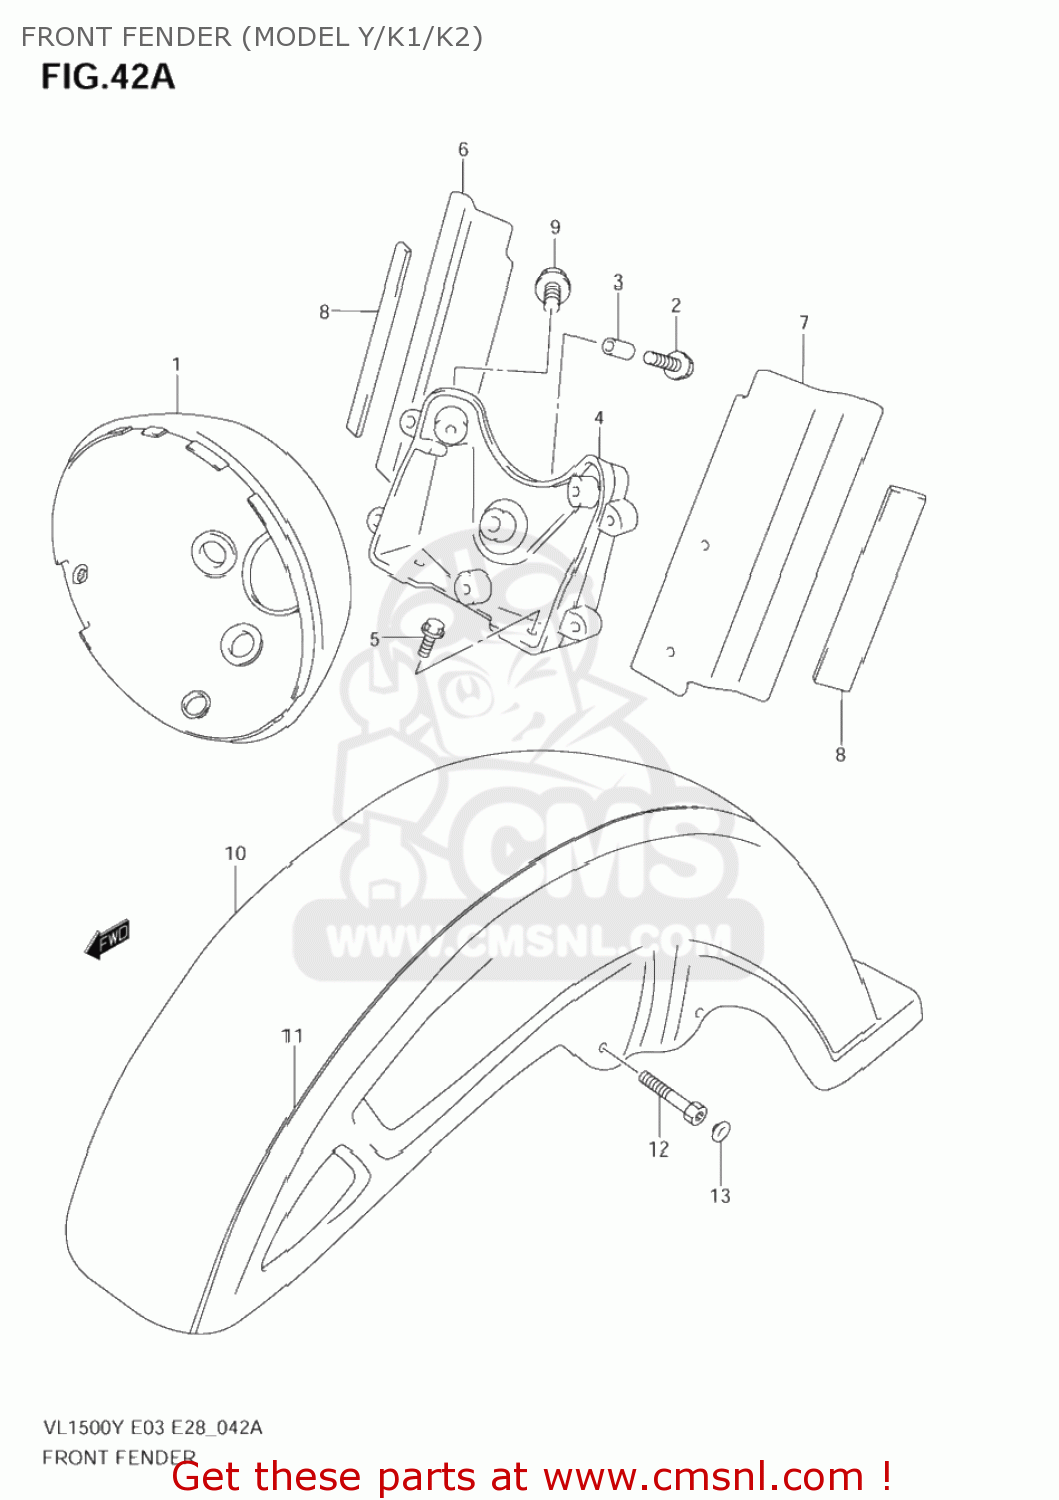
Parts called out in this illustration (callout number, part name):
1	HOUSING,HEADLAMP
2	BOLT(6X25)
3	SPACER(6.8X12X11)
4	BRACKET,HEADLAMP HOUSING
5	BOLT
6	PLATE,HEADLAMP BRACKET,R
7	PLATE,HEADLAMP BRACKET,L
8	PROTECTOR(170X95X3.0)
9	SCREW(6X12)
10	FENDER COMP,FR
11	TAPE SET,FR FENDER
12	BOLT
13	CAP(OD:11)
